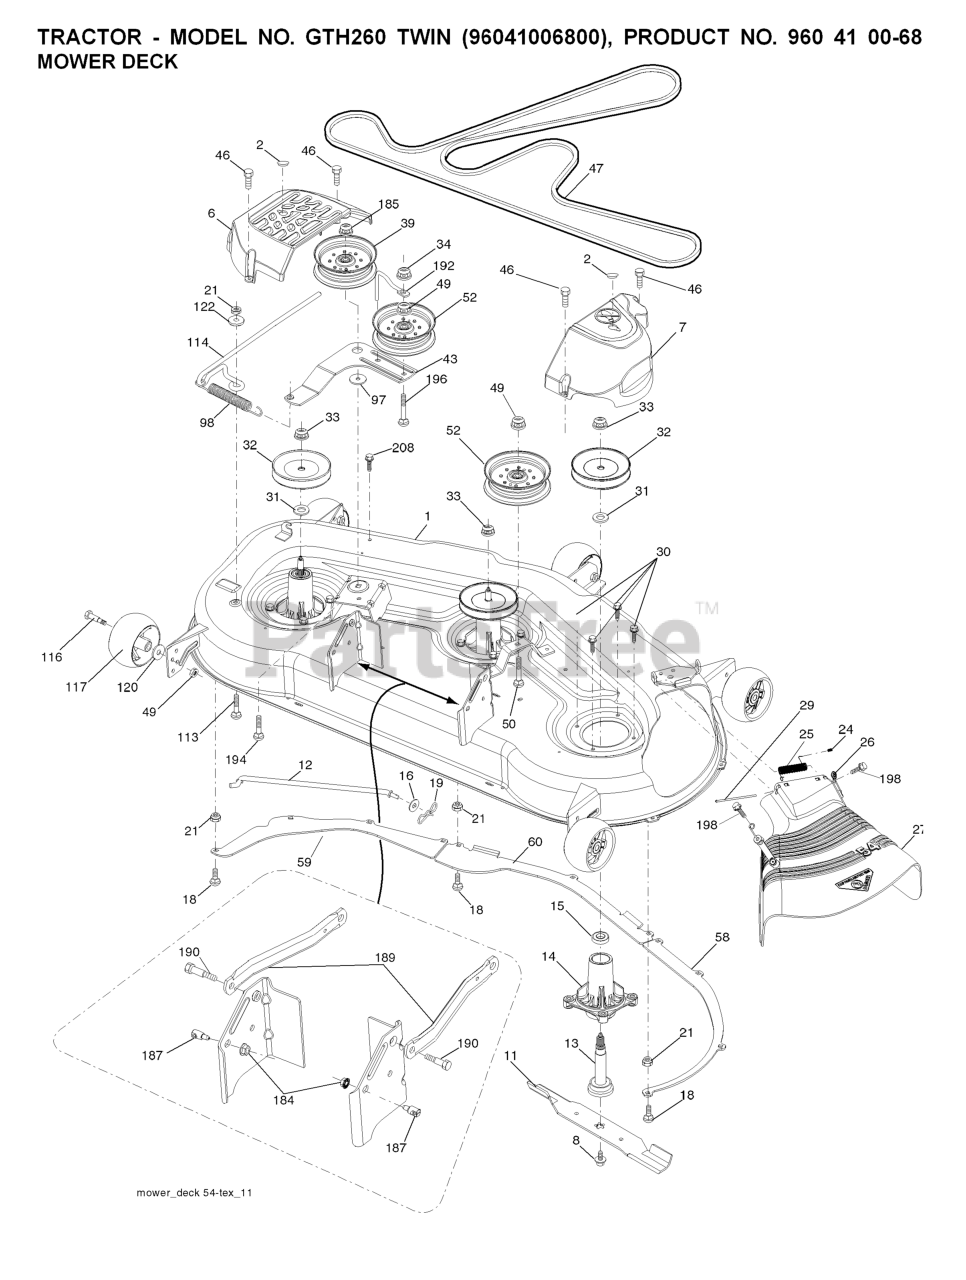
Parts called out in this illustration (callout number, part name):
1	TUBE.HANDLE.LOOP.LH.GRAY
2	TUBE.HANDLE.LOOP.RH.GREY
3	HEX BOLT
4	NUT.LOCK.5/16-18
